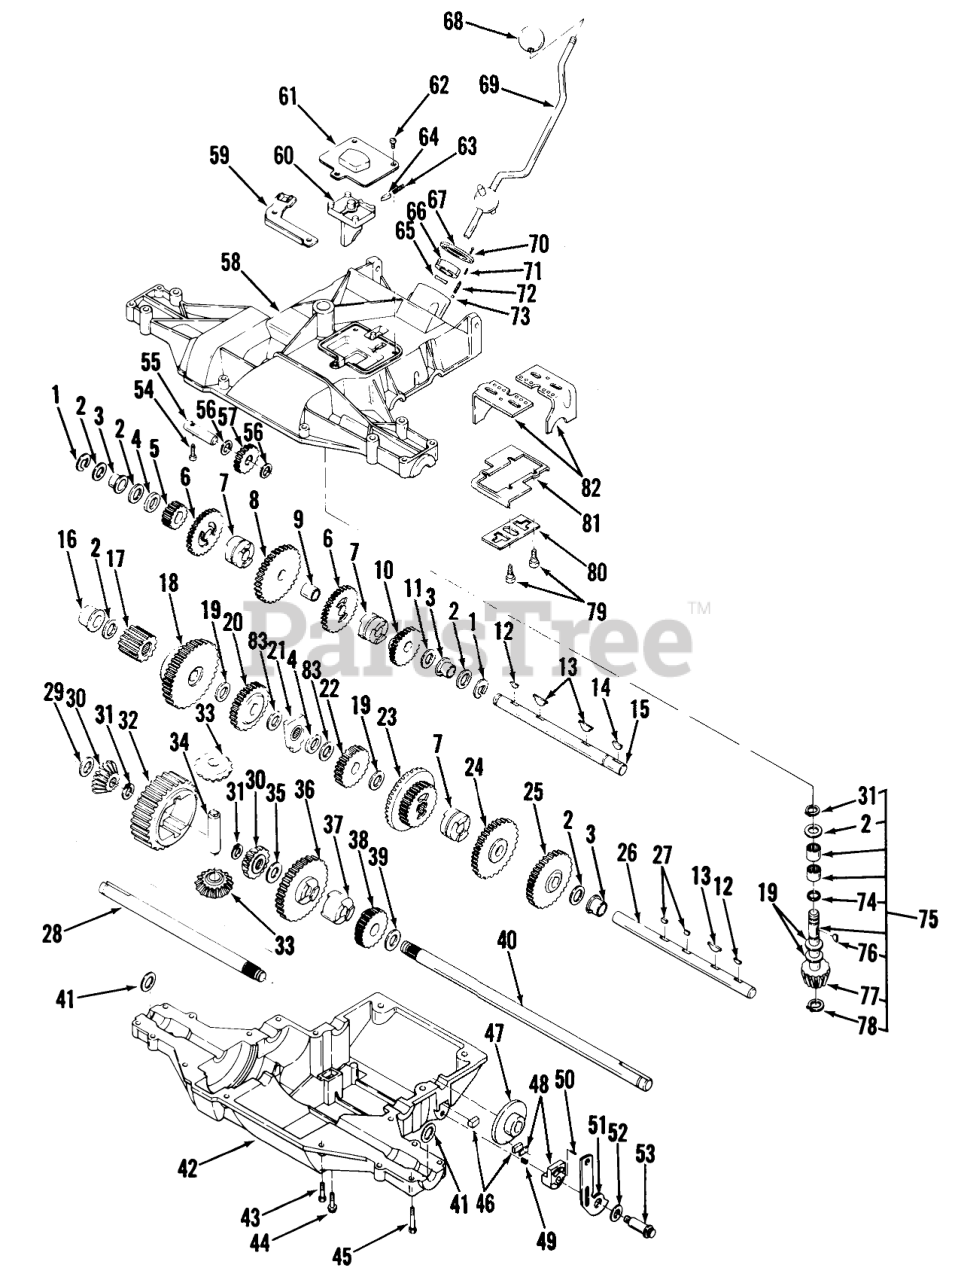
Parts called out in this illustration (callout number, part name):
1	E-Ring
2	WASHER
2	Shim Washer .035
3	Flange Bearing
4	SPACER
5	Spur Gear 13T
6	Spur Gear 25T
7	COLLAR-CLUTCH
8	Spur Gear 30T
9	SPACER 87X632X679
10	GEAR-20T SPUR
11	WASHER
12	KEY-WDRF 3 ALLOY
13	KEY-HI PRO SPECIAL
14	KEY-WDRF 61
15	Intermediate Shaft
16	Flange Bearing
17	Gear Assy. 12T
18	Spur Gear 37T
19	WASHER
20	Spur Gear 25T
21	Shaft Support Assy.
22	GEAR-SPUR 20T
23	Bevel Gear Assy
24	Spur Gear 33T
25	GEAR-SPUR 30T
26	SHAFT-DRIVE
27	WOODRUFF KEY #3
28	Axle LH
29	Shim Washer 1.25 X .755 X .062
29	Shim Washer 1.25 X .755 X .031
29	SHIM WASHER
30	GEAR-MITER SPLINED
31	RETAINING RING
32	GEAR-SPUR 32T
33	Bevel Gear 15T
34	SHAFT-CROSS
35	Shim Washer 1.25 X .755 X .031
36	GEAR-SPUR 35T
37	Gear Lock
38	Spur Gear 22T
39	Shim Washer 1.25 X .755 X .062
40	Axle RH
41	SEAL-FELT
42	Case Half, Lower
43	S.T. Bolt 1/4-20 X 3/4
44	Hex HD. Machine Screw #12-24 X 5/8
45	S.T. Bolt 1/4-20 X 1 5/16
46	Friction Puck
47	DISC-BRAKE
48	ASSY-BRAKE JAW
49	SPRING-COMPRESSION
50	SCREW-SET 8-32
51	Brake Lever
52	Shim Washer .750 X .505 X .015
52	WASHER-PLAIN
53	Shoulder Bolt
54	SCREW 10-24X1 TAPPNG
55	SHAFT-IDLER
56	WASHER-PLAIN 1X.505
57	Idler Gear Assembly
58	HOUSING-UPPER
59	Lever, HI-Lo Shift
60	Shift Fork, HI-Lo
61	Cover Plate
62	S.T. Bolt #8-32 X 1/2
63	Detent Spring
64	Detent Pin
65	WASHER-WAVE
66	INSERT-NYLON
67	Nylon Cover
68	Knob
69	ASSY-SHIFT LEVER
70	SCREW 10-24X1/2
71	Set Screw 1/4-20 X 1/2
72	SPRING-DETENT
73	Detent Ball
74	O-Ring
75	Input Shaft Kit
76	Woodruff Key #9
77	Bevel Pinion 16T
78	RING-RETAINING
79	SCREW 1/4-28X3/4
80	PLATE LOCK-OUT
81	PLATE-FORK SUPPORT
82	FORK SHIFTER
83	WASHER
